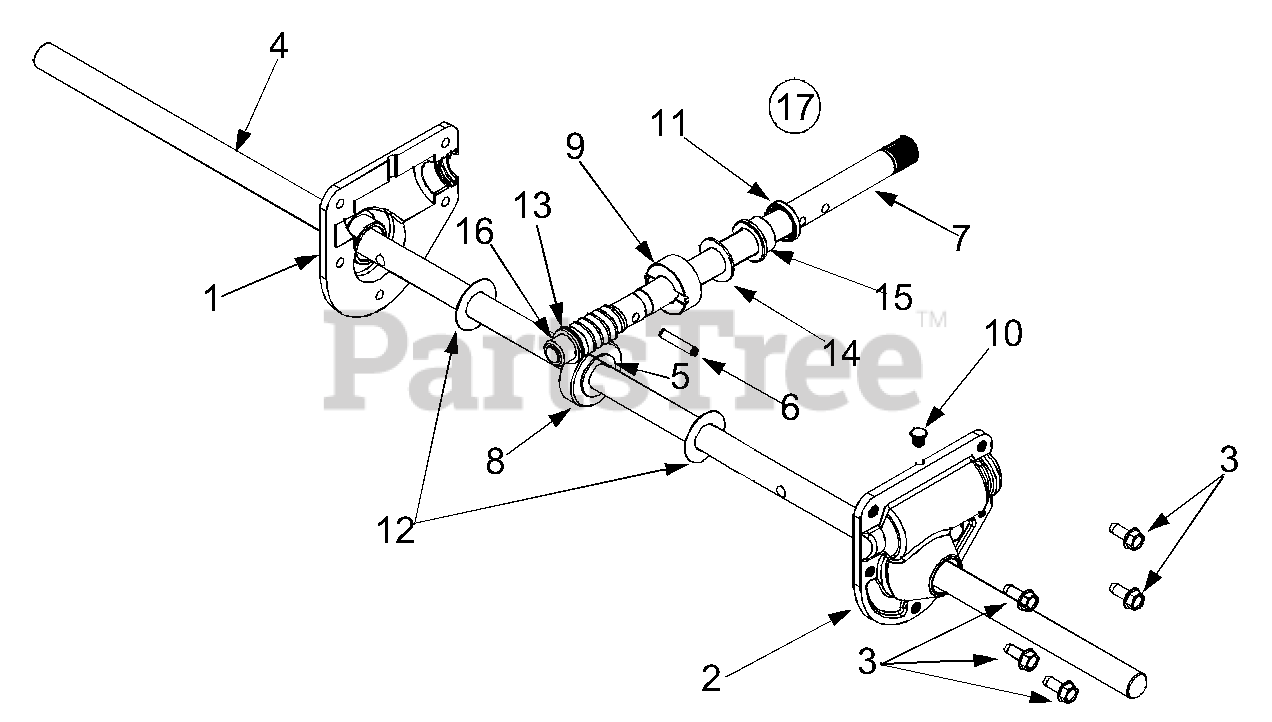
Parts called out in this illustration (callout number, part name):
1	Housing-R.H.
2	Housing-L.H.
3	Hex Screw 1/4-20 x.75
4	Spiral Axle 24"
5	Key
6	Spiral Pin
7	Worm Shaft
8	Worm Gear
9	Thrust Collar
11	Oil Seal
12	Flat Washer
13	Flat Washer
14	Flat Washer
15	Flange Bearing
16	Flange Bearing
17	Ass'y. Complete 24"
